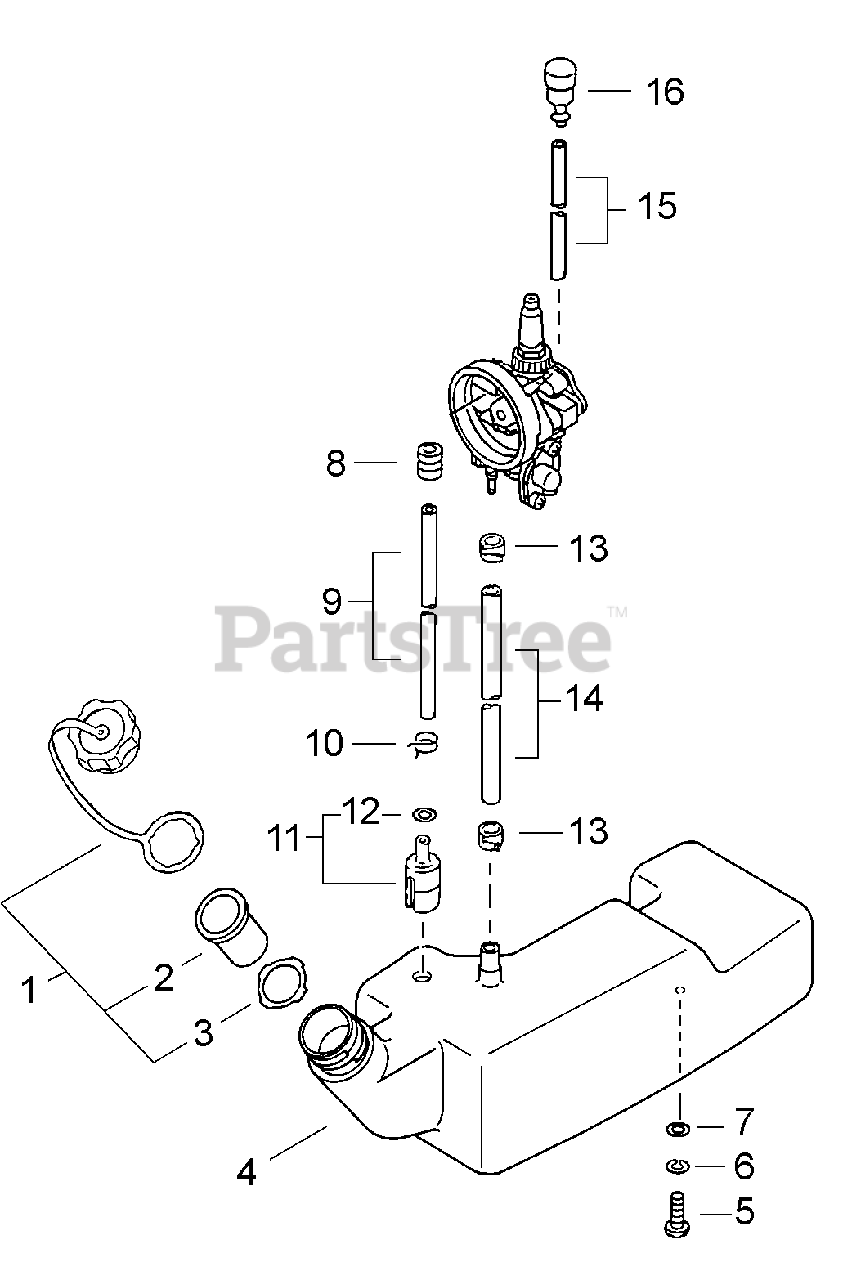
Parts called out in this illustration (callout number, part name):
1	CAP ASSY, FUEL
2	CAP, VENT
3	GASKET, FUEL CAP
4	TANK, FUEL
5	SCREW 6×14
6	WASHER, SPRING 6
7	WASHER 6.5×18×1.6
9	PIPE, FUEL 3×6×230
10	CLIP Ø6.5 MM
11	FILTER, FUEL
12	WASHER 5.5×12×0.8
13	CLIP 10.5 MM
15	PIPE, FUEL 3×6×85 BLACK
16	VENT ASSY
